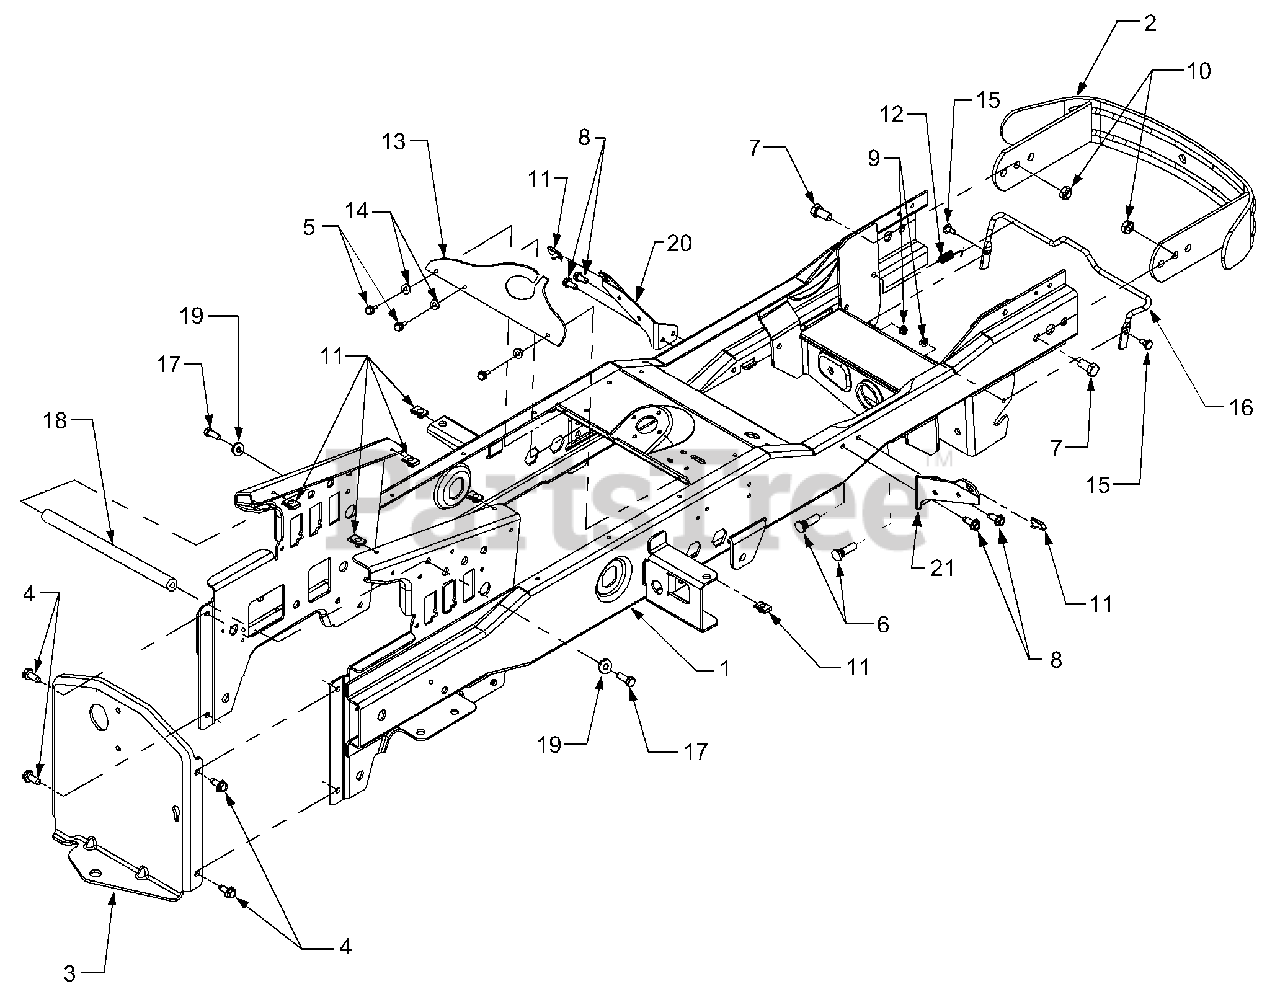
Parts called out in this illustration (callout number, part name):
1	Frame Assembly
2	Bumper, Front
4	Screw, Hex Wash. Hd. Tapp 3/8-16 x .75
5	Screw, Hex Wash. Hd. Tapp 1/4-20 x .5
6	Screw, Round Hd., 3/8-24
7	Screw, Hex Cap 1/2-13 x 1.0 GR5
8	Screw, Hex Wash. Hd. Tapp 5/16-18 x .75
9	Nut, Hex Flange Lock, 1/4-20
10	Nut, Hex Lock, 1/2-13
11	Speed Nut, U-Type, 5/16-18
12	Spring, Extension
13	Flap, Intk.
14	Washer, Flat, .283 x .75 x .030
15	Shoulder Screw, .312 x .18
16	Rod, Front Latch
17	Screw, Hex Cap, 5/16-18 x .875
18	Shaft, Frame Brace
19	Washer, Flat, .344 x .75 x .12
20	Bracket, Running Board LH
21	Bracket, Running Board RH
